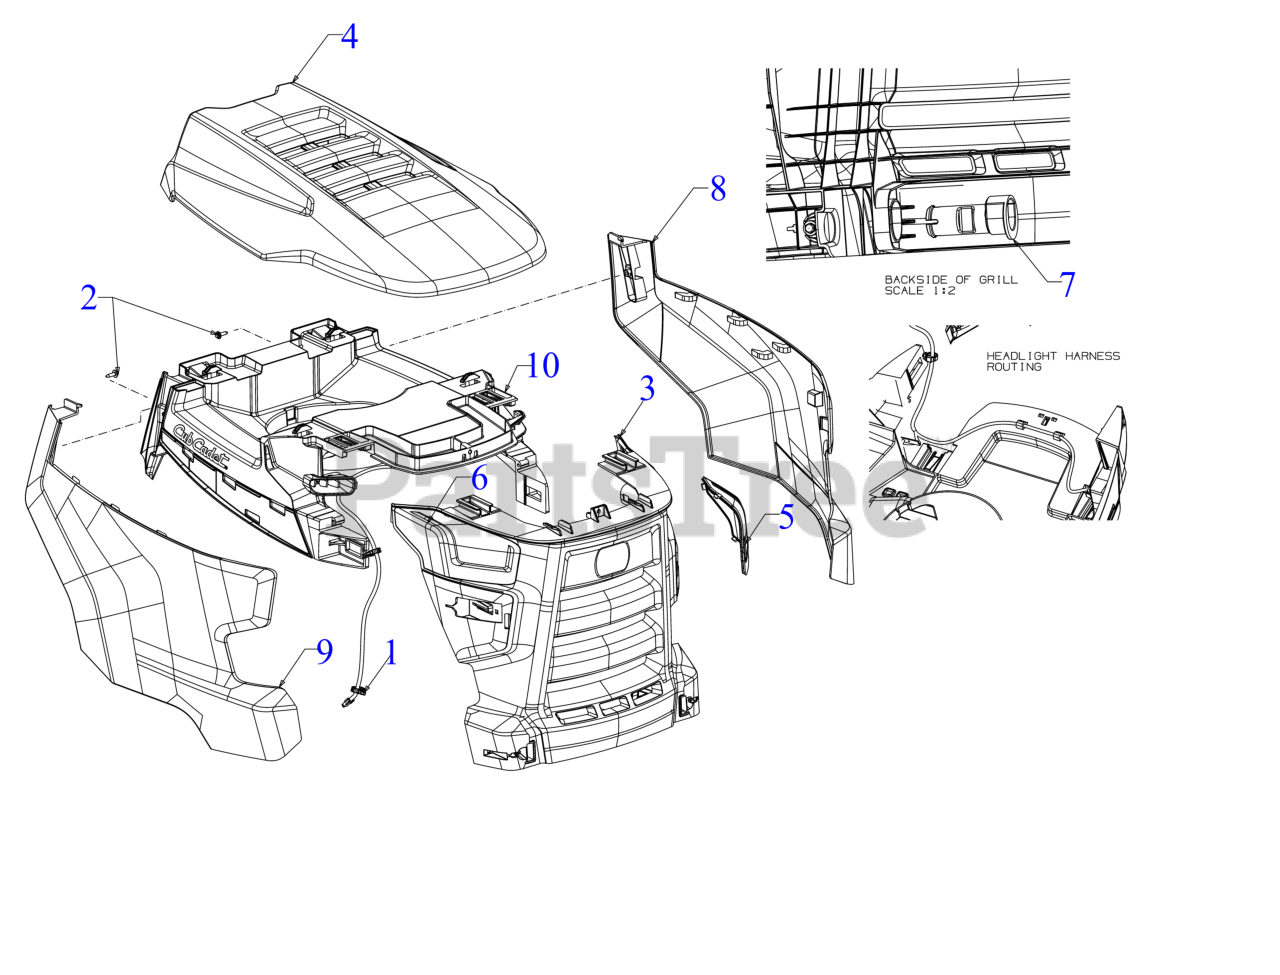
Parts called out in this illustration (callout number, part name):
1	HEADLIGHT HARNESS (W/LED)
2	SCREW 1/4-10 x .750
3	FRONT GRILLE (STYLE C)
4	HOOD TOP (YELLOW)
5	LED HEADLIGHT LENS (LH)
6	LED HEADLIGHT LENS (RH)
7	HOOD PIVOT PIN
8	SIDE PANEL (LH)
9	SIDE PANEL (RH)
10	PLENUM/HOOD FRAME
